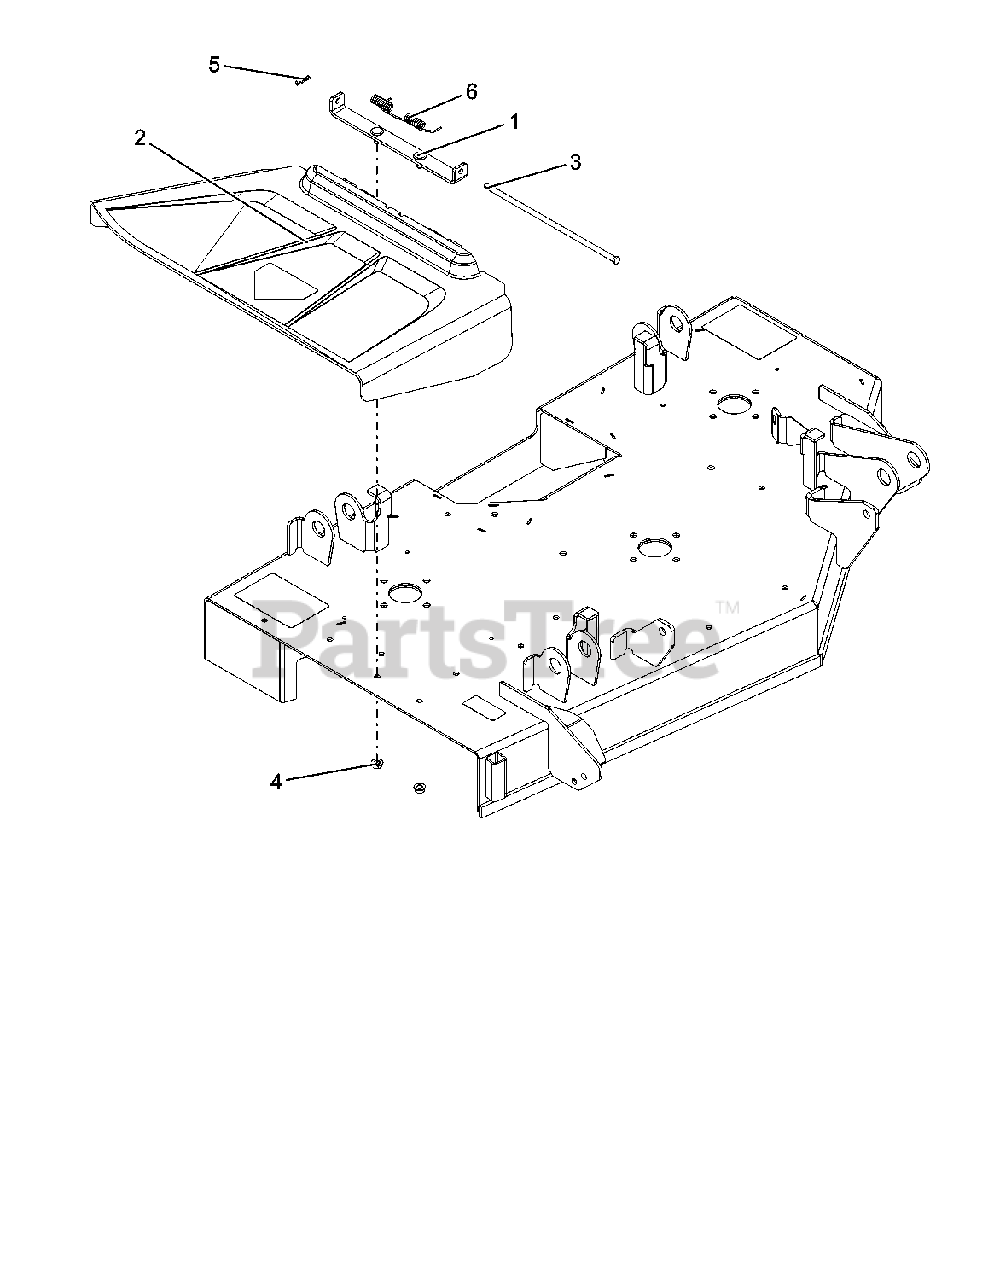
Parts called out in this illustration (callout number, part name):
1	WLDMT, CHUTE MT BRKT
2	CHUTE, SIDE DISCHARGE
3	PIN, 5/16 X 10.5
4	@NUT-LK-TOP-FLG .31-18 YWZC
5	PIN-HAIR INT .08X.18X1.18 YWZC
6	SPRING-TORSION
